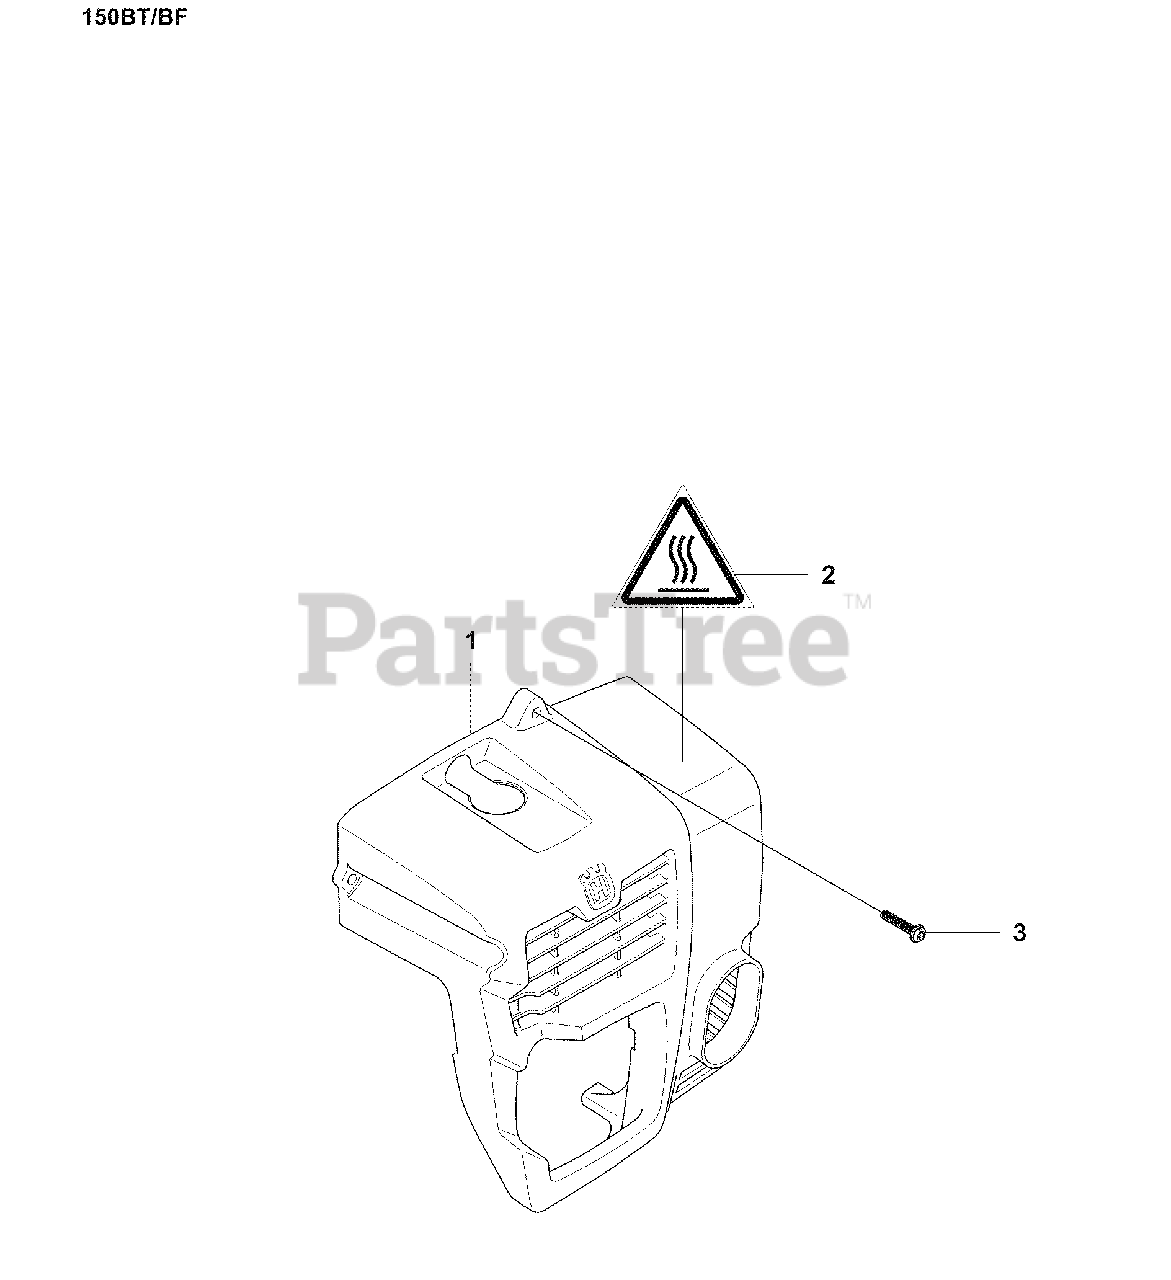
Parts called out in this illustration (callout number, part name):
1	CYLINDER COVER
2	SCREW
3	RP_LABEL, HOTMARK
